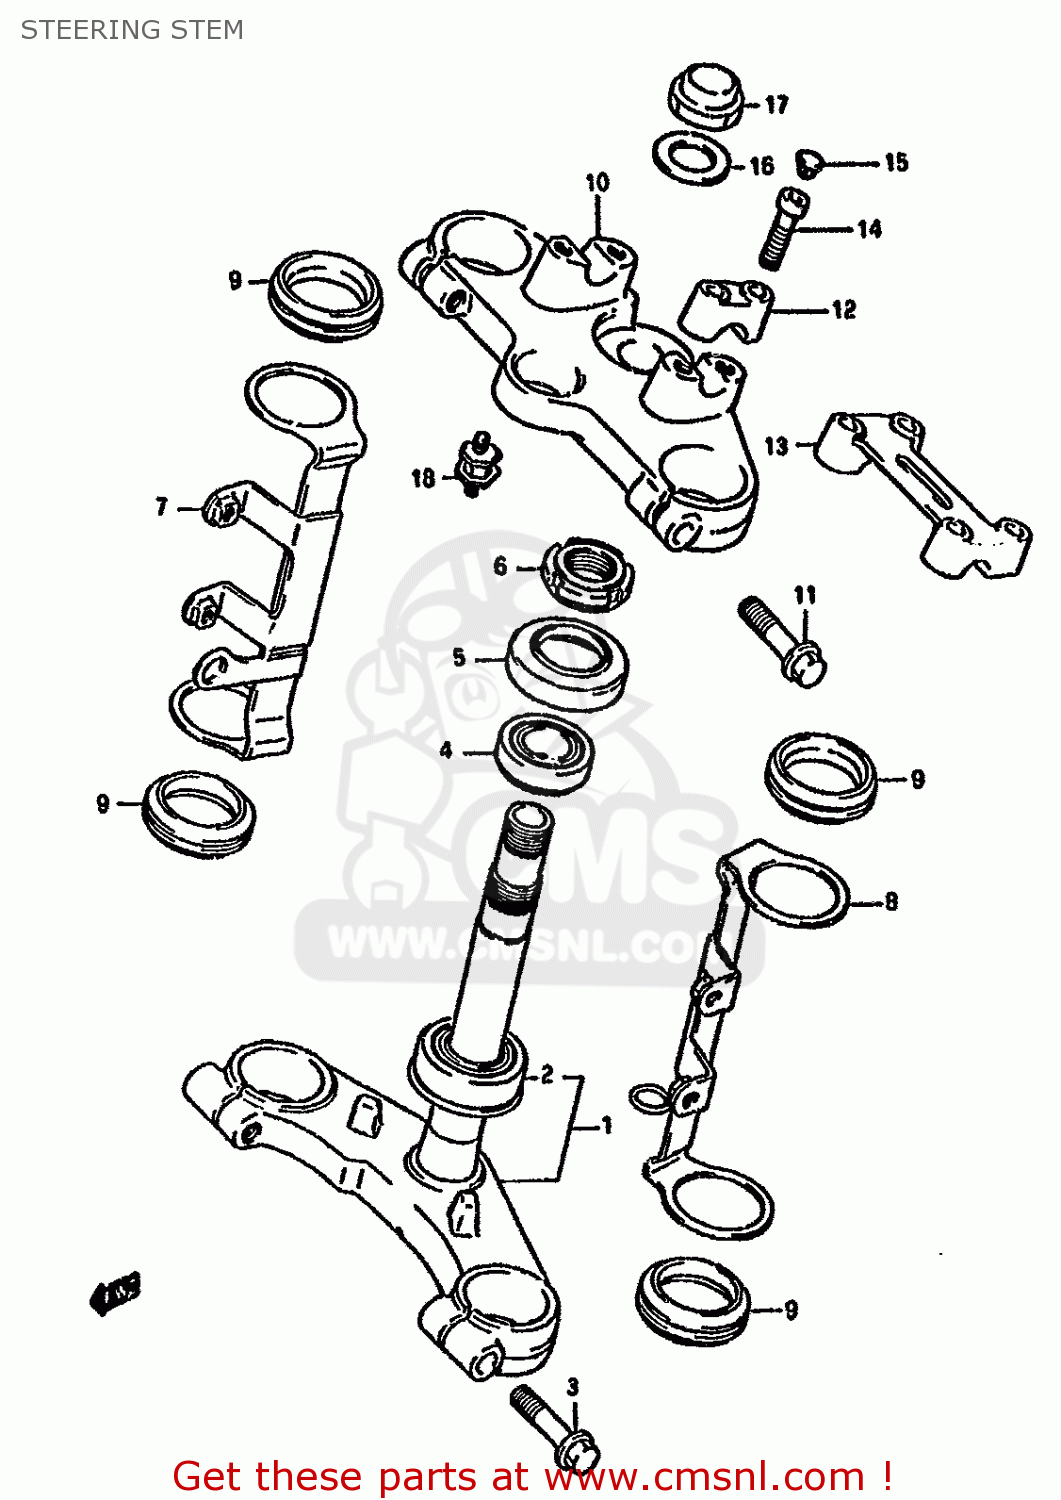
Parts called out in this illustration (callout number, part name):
1	STEM,STEERING
2	BEARING(30X55X17)
3	BOLT 10X45
4	TAPER,ROLLER BEARING
5	DUST SEAL,STEERING UPR
6	NUT,STEERING STEM(25X44X10)
7	BRACKET,HEADLAMP HOUSING,R
8	BRACKET,HEADLAMP HOUSING,L
9	DAMPER,HEADLAMP HSG BRACKET
10	HEAD,STEERING STEM
11	BOLT 10X45
12	HOLDER,HANDLE UPR
13	HOLDER,HANDLE
14	BOLT, LH
15	CAP(OD:11)
16	WASHER,UPPER
17	NUT,CAP
18	BOLT,SPEEDOMETER CUSHION
